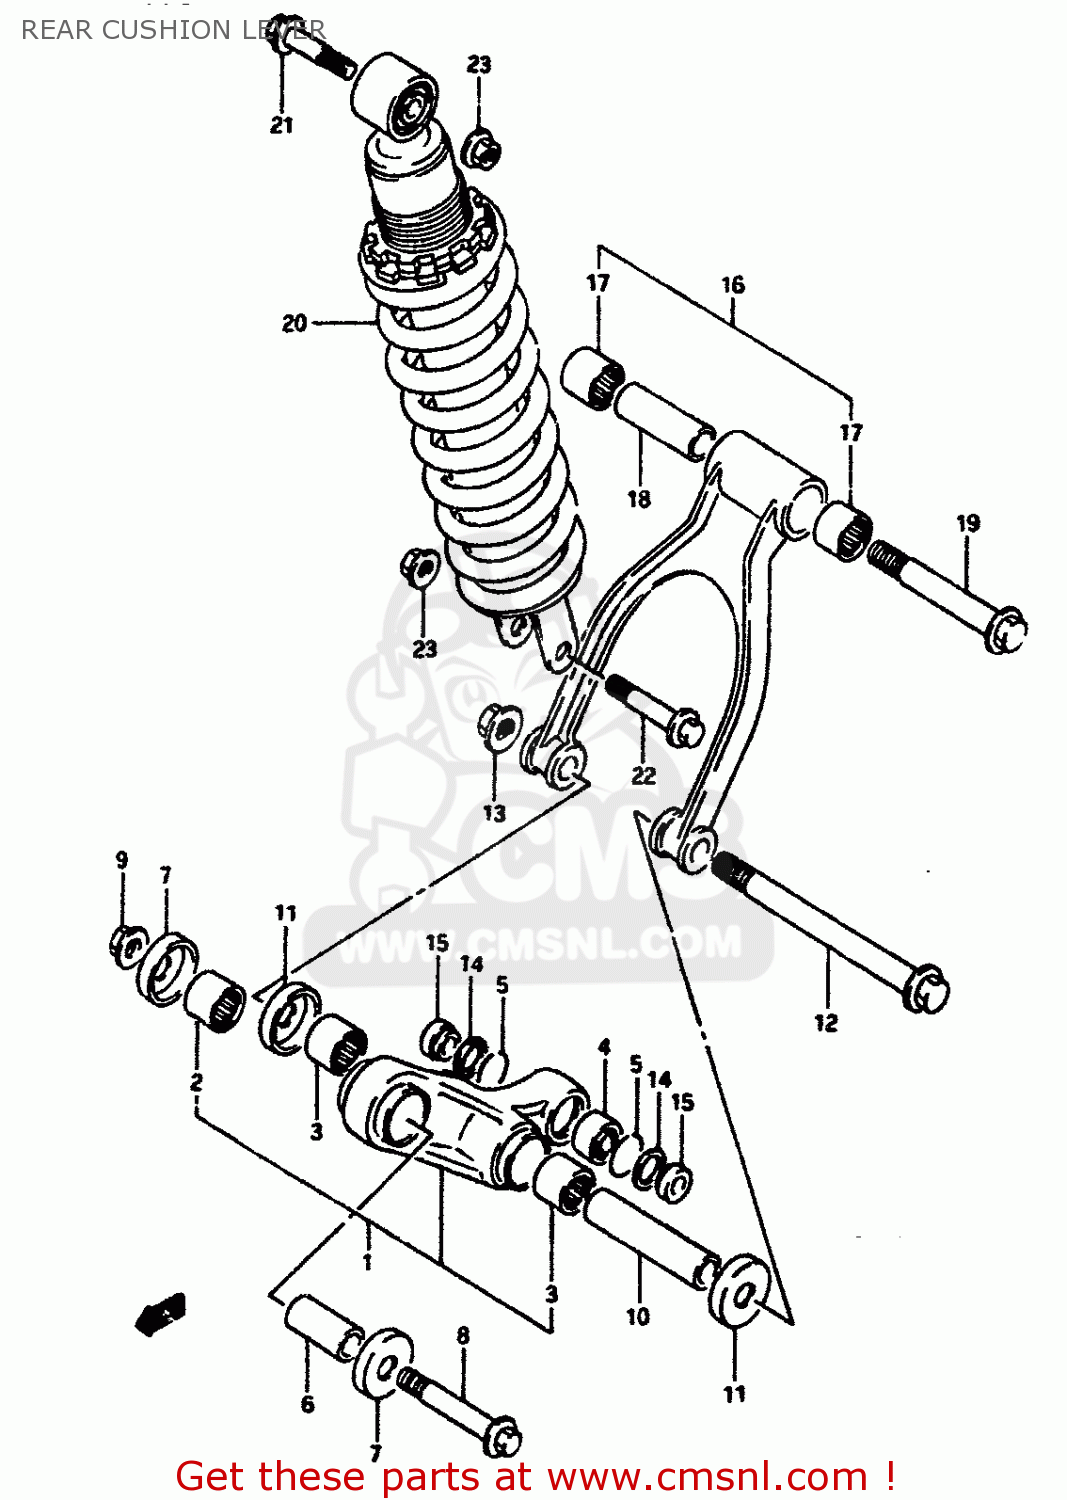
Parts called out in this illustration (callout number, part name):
1	LEVER SET,REAR CUSHION
2	BEARING(20X27X30)
3	BEARING(20X27X23.5)
4	BEARING,REAR SHOCK ABSORBER
5	RING
6	SPACER,RR CUSHION LEVER FR
7	SEAL,RR CUSHION LEVER FR DUST
8	BOLT,RR CUSHION LEVER FR
9	NUT 12MM
10	SPACER (14X20X78)
11	SEAL,RR CUSHION LEVER CTR DUST
12	BOLT,RR CUSHION ROD LWR
13	NUT
14	SEAL,DUST RR SHOCK ABSORBER
15	COLLAR
16	LEVER SET,REAR CUSHION
17	BEARING(20X27X23.5)
18	SPACER (14X20X63)
19	BOLT,RR CUSHION ROD UPR
20	ABSORBER,SHOCK
21	BOLT(10X50)
22	BOLT(10X52)
23	NUT
